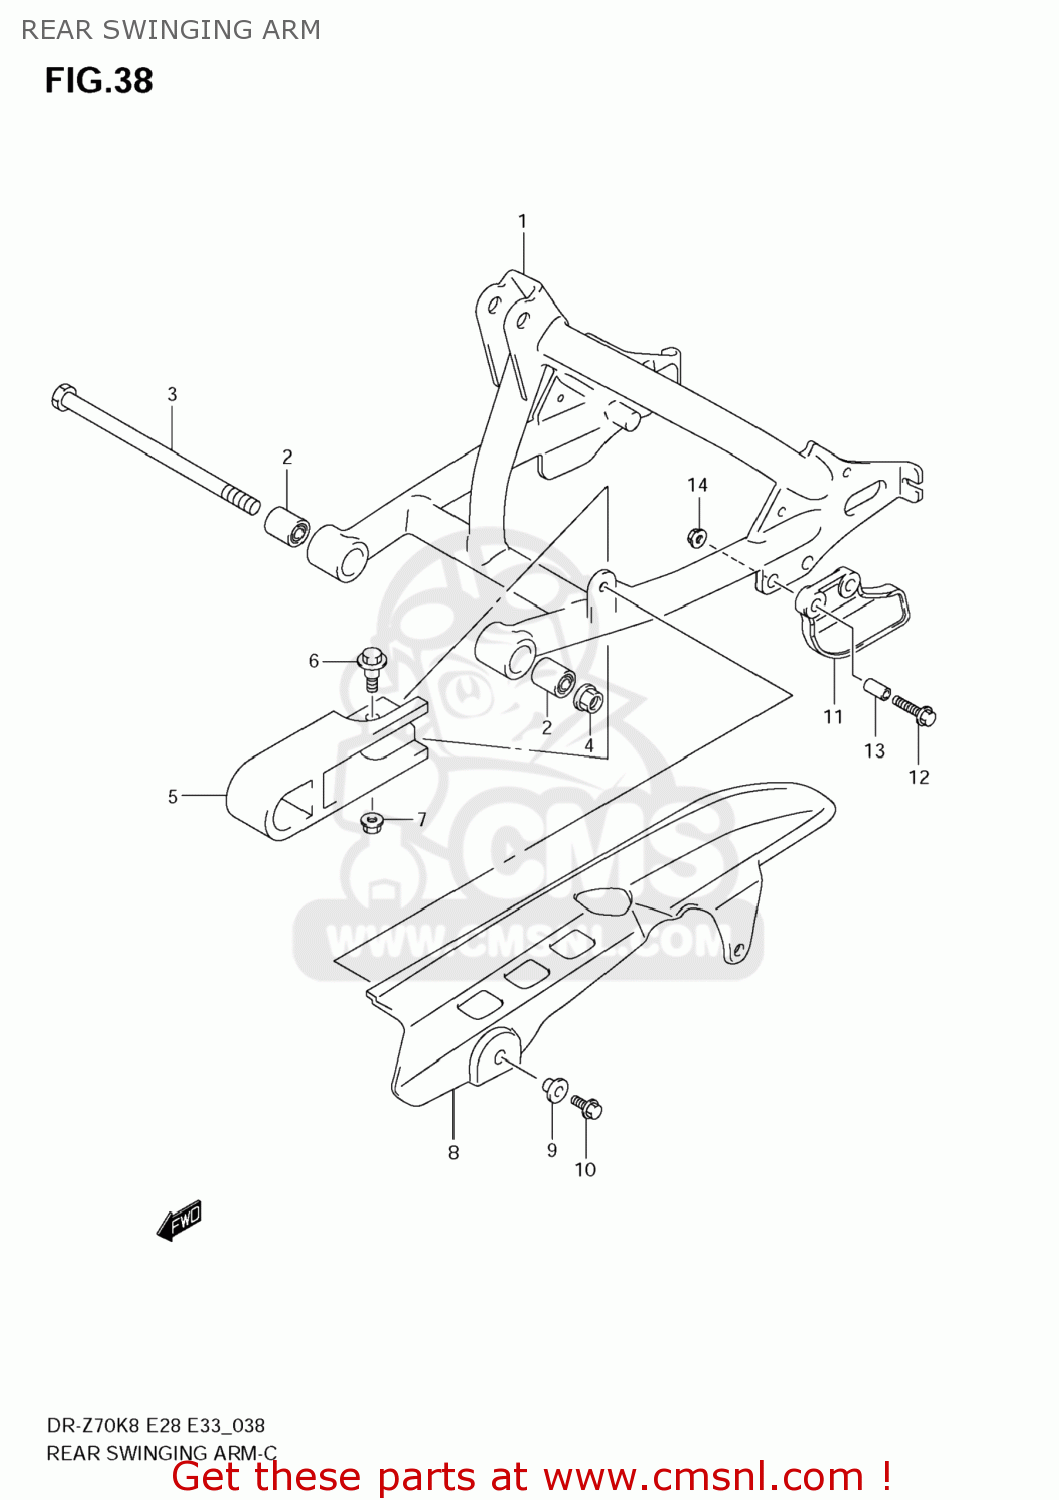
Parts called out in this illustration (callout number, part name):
1	ACHTERVORK
2	BUSH(10X23X30)
3	SHAFT,RR SWINGINGARM PIVOT
4	NUT
5	BUFFER,CHAIN TOUCH DEFENSE
6	BOLT(6X19)
7	NUT
8	CASE,CHAIN
9	WASHER
10	BOLT
11	GUIDE,CHAIN
12	BOLT(6X25)
13	SPACER(6.1X8X15)
14	NUT
